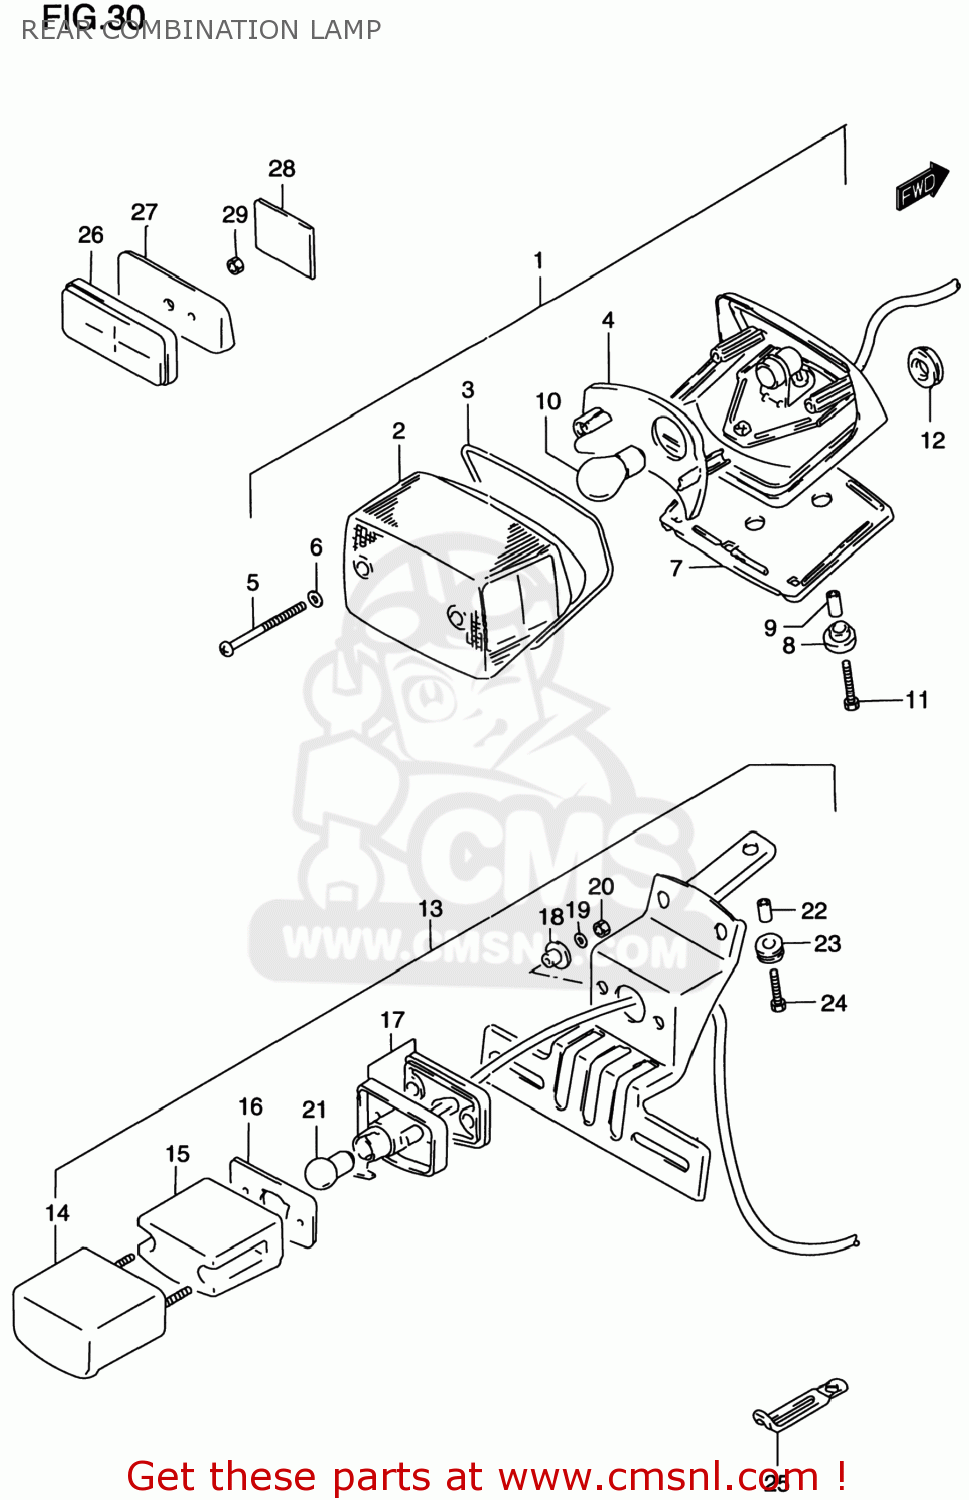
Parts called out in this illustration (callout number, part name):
1	LAMP ASSY,RR COMBINATION
2	LENS
3	GASKET (NAS)
4	REFLECTOR
5	SCREW
6	GASKET (NAS)
7	CUSHION
8	CUSHION
9	SPACER
10	BULB(12V21/5W,BF141-49642A)
11	BOLT(6X25)
12	GROMMET
13	LAMP ASSY,LICENSE
14	COVER,LICENSE LAMP
15	LENS
16	GASKET,LICENSE LAMP (NAS)
17	HOUSING,LICENSE LAMP
18	SPACER
19	WASHER,LOCK
20	NUT
21	BULB(12V8W)
22	SPACER
23	CUSHION
24	BOLT(6X20)
25	CLAMP(L:45)
26	REFLECTOR ASSY,RR
27	SPACER,RR REFLECTOR
28	TAPE,TOOL BAG PROTECTOR
29	NUT
